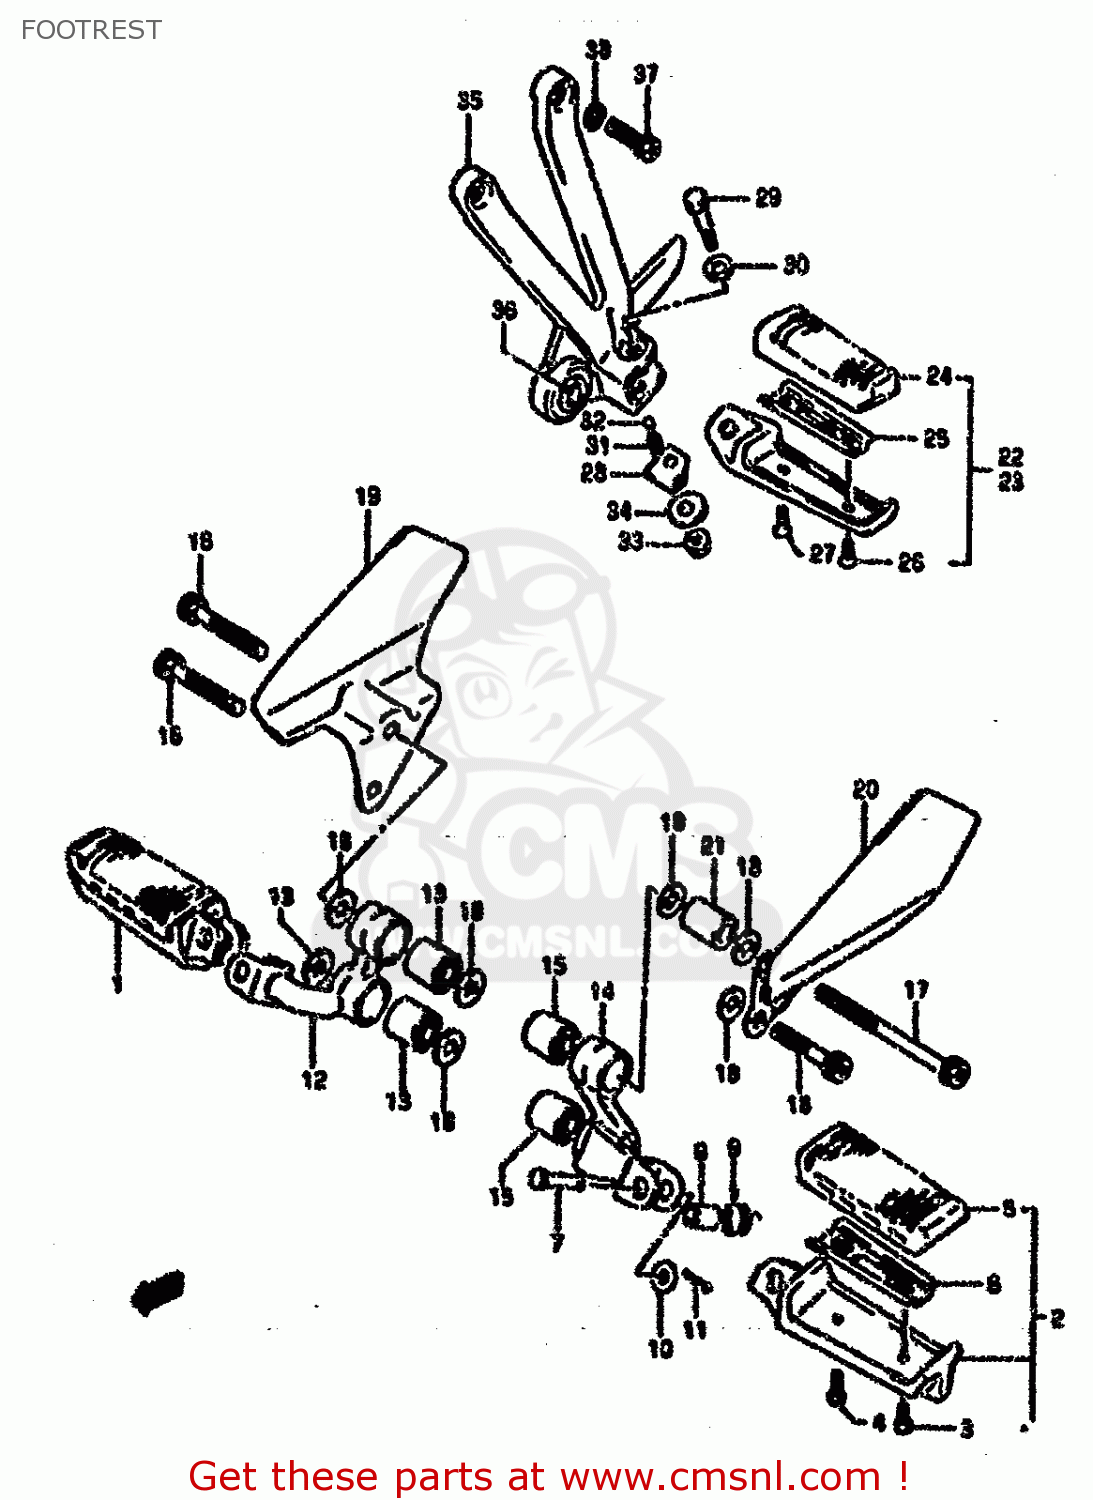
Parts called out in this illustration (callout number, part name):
1	FOOTREST ASSY,FR,R
2	FOOTREST ASSY,FR,L
3	SCREW
4	SCREW
5	RUBBER,FOOTREST
6	PLATE,FR FOOTREST RUBBER
7	PIN
8	SPACER(8.1X12X22)
9	SPRING
10	WASHER
11	PIN 20X20
12	HOLDER,FR FOOTREST,R
13	BUSH
14	HOLDER,FR FOOTREST,L
15	BUSH
16	BOLT
17	BOLT
18	WASHER(10.5X22X2.3)
19	FOOTREST
20	CUSHION,FRONT FOOTREST
21	SPACER,FR FOOTREST GUARD,L
22	FOOTREST ASSY,PILLION,R
23	FOOTREST ASSY,PILLION,L
24	RUBBER,RR FOOTREST
25	PLATE,RUBBER STOPPER
26	SCREW
27	SCREW
28	PLATE,SPRING STOP,R
29	BOLT(6X45)
30	SHIM(8.2X22X0.2)
31	SPRING
32	BALL
33	NUT
34	WASHER
35	BRACKET,PILLION FOOTREST
36	BUSH(10.2X25X19)
37	BOLT
38	WASHER
